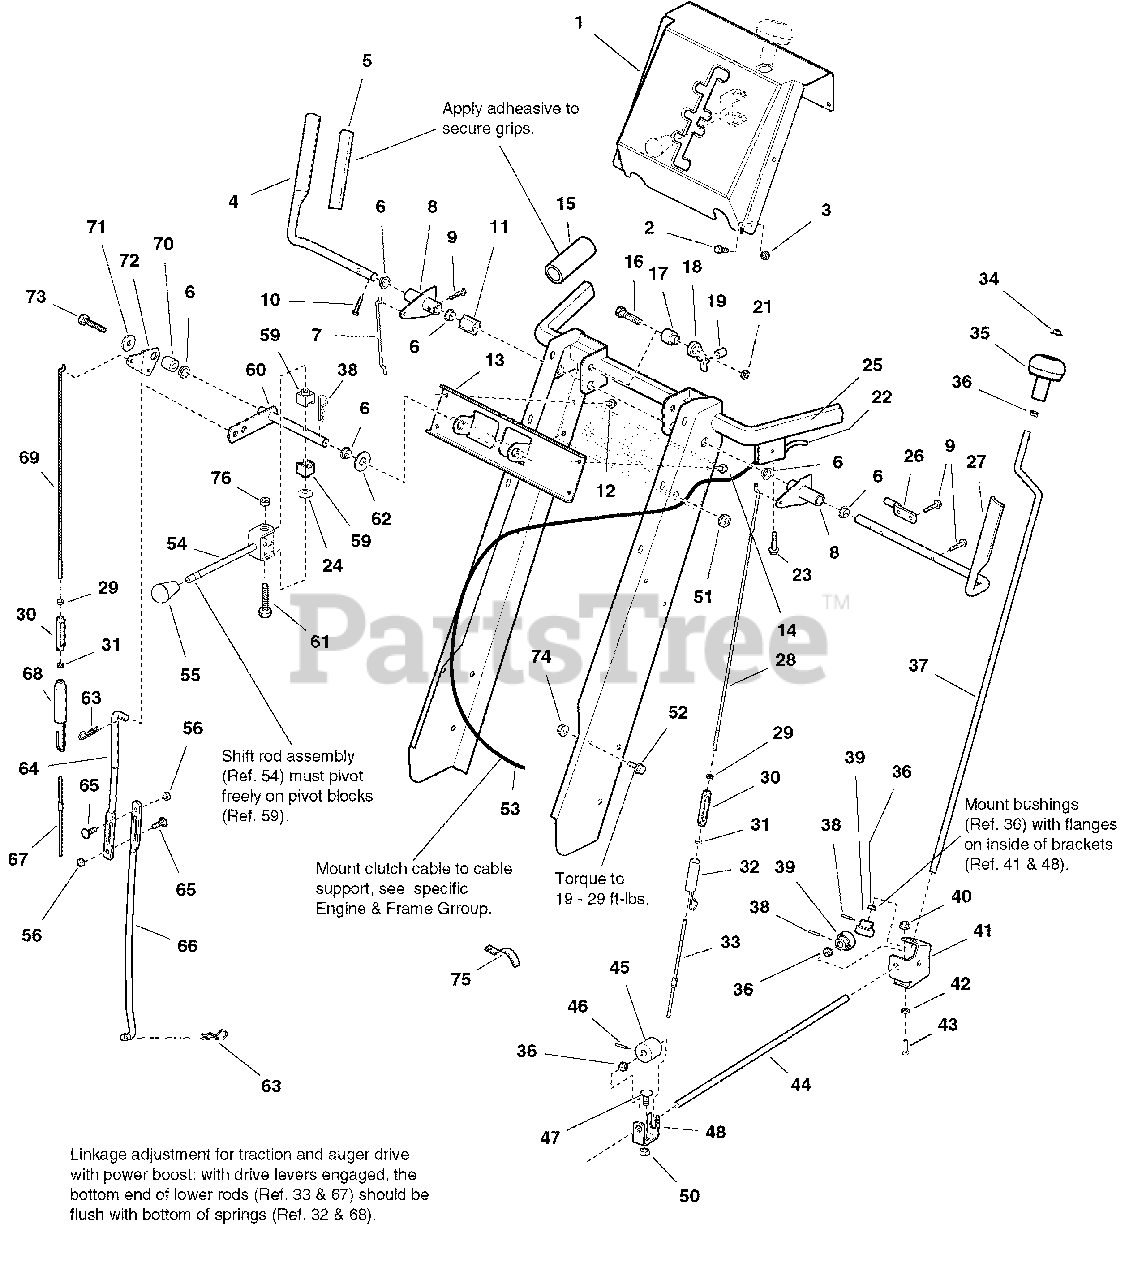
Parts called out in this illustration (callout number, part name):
2	CAPSCREW, Hex Head, 1/4-20 x 3/4
3	NUT, Whiz Lock 1/4-20
4	HANDLE, Clutch, RH
6	BUSHING, Nylon
7	ROD, Clutch
8	LEVER & TUBE ASSEMBLY, Clutch
9	CAPSCREW, Hex Washer Head, #12-24 x 1
10	CAPSCREW, Hex Washer Head, #10-24 x 1
11	GUIDE, Control
12	CAPSCREW, Hex Washer Head, Taptite, 1/4-20 x 3/4
13	BRACKET, Shift Control
14	CAPSCREW, Hex Washer Head, Taptite, 1/4-20 x 3/4
16	SCREW, Hex Whiz Lock Flange 5/16-18 x 1 1/2
17	SPACER
18	LATCH, Control
19	SPRING, Compression
21	NUT, Hex Flange 5/16-18 ESNA, Black
22	TRIGGER ASSEMBLY, Easy Turn Clutch Cable
23	SCREW, Pan Head, #10 x 1/2
24	WASHER, Curved, 1/2
25	HANDLE ASSEMBLY
26	ROD, Control
27	HANDLE, Clutch, LH
28	ROD, 17-5/16 Long
29	NUT, LH, Machine Screw, Hex, #10-24
31	NUT, RH, Machine Screw, Hex, #10-24
33	ROD, Clutch
34	PUSH NUT
35	KNOB, Spinner
36	BUSHING, Nylon
37	ROD, Chute Control
38	PIN, Hair
40	NUT, Hex Flange, 1/4-20
41	SUPPORT, Gear
42	PUSH NUT
43	CARRIAGE BOLT, 1/4-20 x 5/8
46	PIN, Spring, 1/8 x 3/4
47	CARRIAGE BOLT, 5/16-18 x 3/4
48	SUPPORT, Worm
50	NUT, KEPS Washer 5/16-18
52	CAPSCREW, Hex Whiz Lock, 5/16-18 x 3/4
53	CABLE & HANDLE ASSEMBLY, Clutch (Includes Reference Number 22)
54	SHIFT ASSEMBLY, Rod & Clevis
56	NUT, KEPS, 1/4-20, Conical Washer, Black
59	BLOCK, Pivot
60	ROD & ARM ASSEMBLY, Pivot
61	CASPSCREW- Hex Head 1/4-20 x 2 1/4, Black
62	WASHER, 1/2
63	PIN, Quick
64	ROD, Shift, Upper
65	CARRIAGE BOLT, 1/4-20 x 3/4
66	ROD, Shift, Lower
67	ROD, Clutch, Lower
69	ROD, Clutch, Upper
71	WASHER, 5/16
72	LEVER, Clutch
73	SCREW, Hex Head Whiz Lock Flange, 5/16-18 x 1 1/2
74	NUT, Hex Flange, 5/16-18
75	CLIP, Wire
76	NUT, Hex Falnge 1/4-20 ESNA, Yellow
